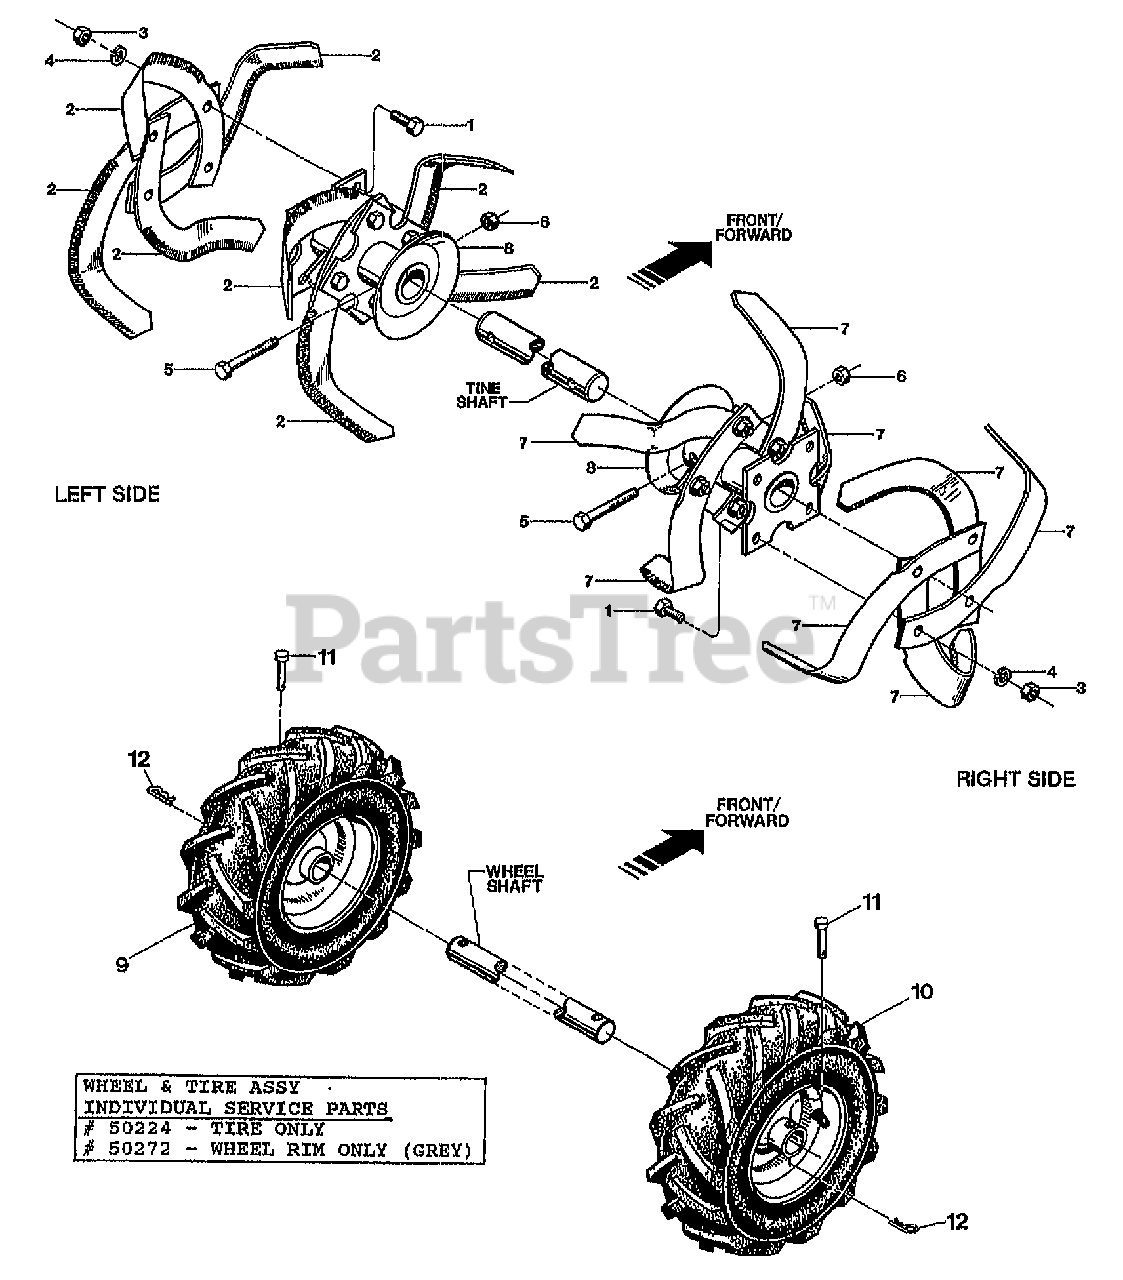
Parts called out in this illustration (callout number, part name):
1	SCR-HH 3/8-16X1.0 G5 ZP
2	TINE-BOLO RIGHT
3	NUT-HEX 3/8-16 ZP
4	WASHER-LK .375 @ DEPL
5	SCR-HH 3/8-16X2.00 G8
6	NUT-H/LK 3/8-16
7	TINE-BOLO LEFT
8	HOLDER-TINE JUNIOR
9	ASSM-TIRE&WHEEL LH GRAY
10	ASSM-TIRE&WHEEL RH GRAY
11	PIN-CLEVIS
12	PIN-CLIP .08
